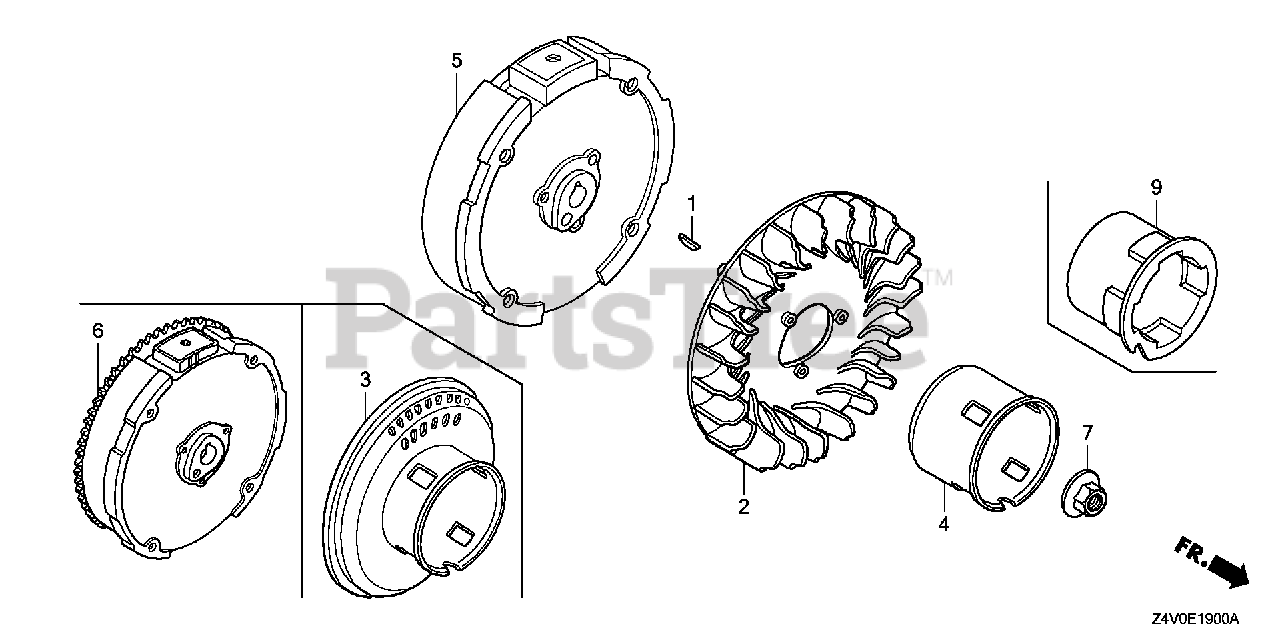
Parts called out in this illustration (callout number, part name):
1	KEY, SPECIAL WOODRUFF (25X18)
2	FAN, COOLING
4	PULLEY, STARTER
5	FLYWHEEL (STD)
7	NUT, SPECIAL (14MM)
